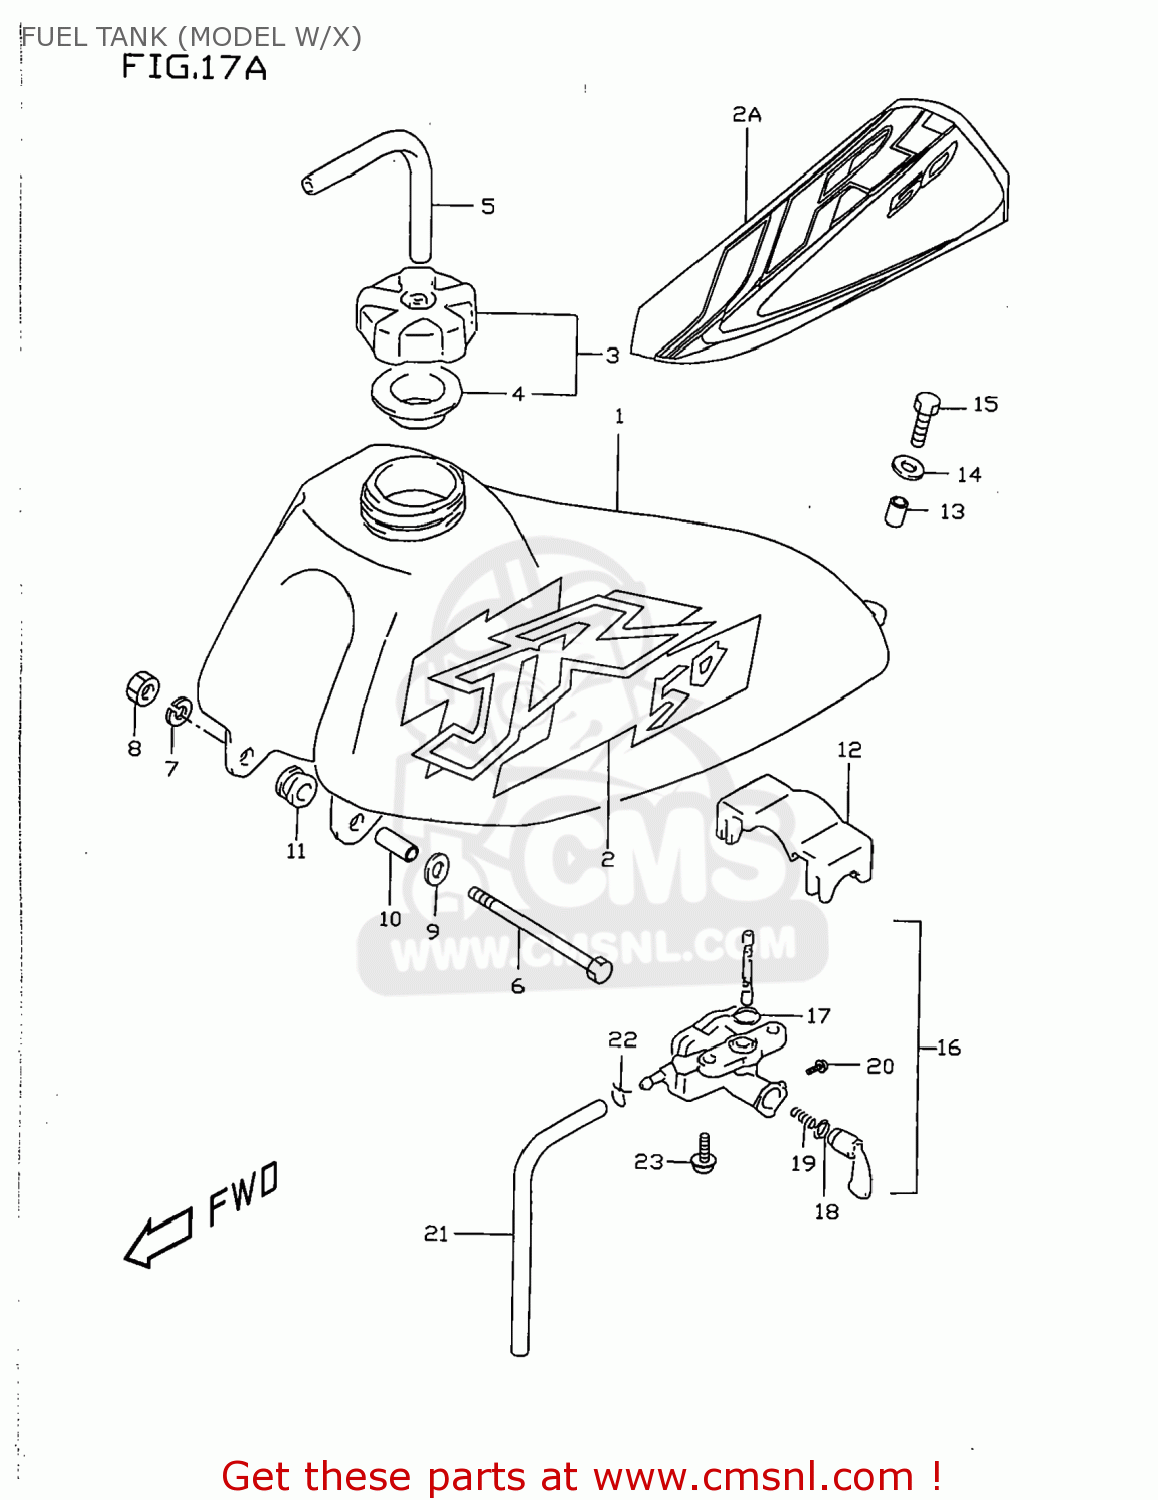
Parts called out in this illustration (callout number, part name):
1	TANK,FUEL
2	EMBLEM SET,FUEL TANK
2A	EMBLEM SET,FUEL TANK
3	CAP,FUEL TANK FILLER
4	GASKET (NAS)
5	HOSE(5X8.2X600)
6	BOLT, FRONT
7	LOCK WASHER
8	NUT 6MM
9	WASHER(6.5X18X1)
10	SPACER(6.5X10X11.5)
11	CUSHION
12	CUSHION,FUEL TANK UPR
13	SPACER(6.5X9X7.2)
14	WASHER(6.5X18X1)
15	BOLT
16	COCK ASSY,FUEL
17	O RING
18	O RING,LEVER
19	SPRING
20	SCREW
21	HOSE(5X8.2X600)
22	CLIP
23	SCREW
